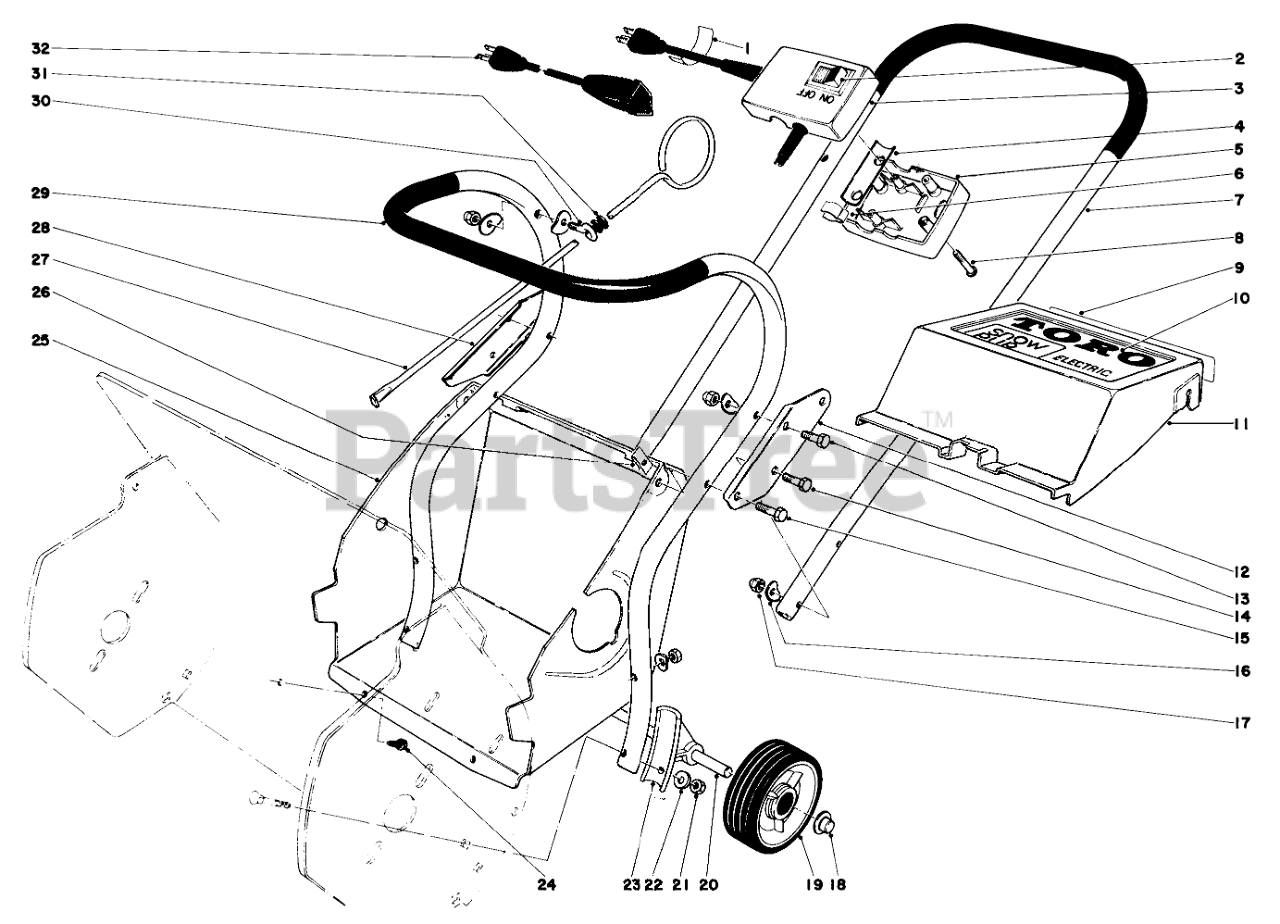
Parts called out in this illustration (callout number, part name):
1	Decal
2	Switch-Single Throw
3	Switch Housing Upper
4	Insert Switch Housing
5	Switch Housing Lower
7	Upper Handle
9	Decal-Caution
10	Decal
11	Upper Shroud Incl. Ref. #9 & 10
12	SPLICE PLATE
13	Capscrew
14	Nut
16	WASHER
17	NUT-CAP
18	RETAINER-PUSH ON
19	Wheel
21	Nut
22	WASHER-FLAT
23	Wheel Bracket
24	SCREW-HWHTF
25	Lower Shroud
26	NUT-SPEED
27	Vane Adj. Rod
28	Plate-Splice
29	Lower Handle
30	Bolt-Eye
31	GROMMET
32	100 Ft. Cord
